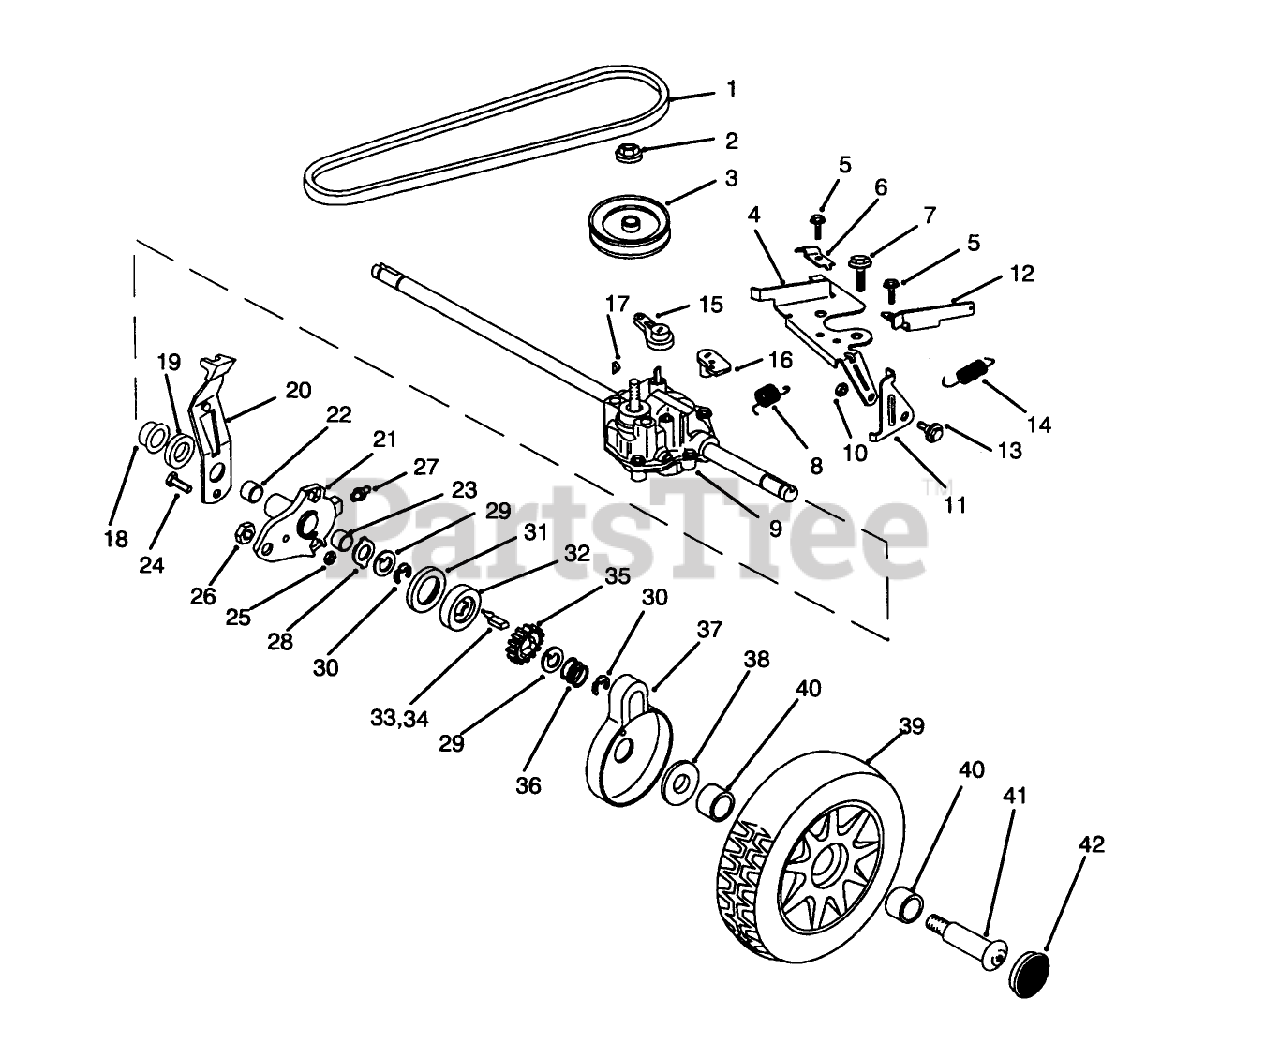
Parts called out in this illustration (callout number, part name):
1	V BELT SM
3	PULLEY TRANS ADAMS
6	CLAMP-CABLE
10	NUT-LOCK, NI
16	ARM - CLUTCH
17	KEY GALGER
18	RING ISO
19	SPACER-SHAFT, AXLE
20	KNOB&SPRING AY.
24	SCREW-HWH
25	NUT-LOCK, NI
26	NUT-JAM, LOCKING
28	WASHER-ARM, PIVOT
29	WASHER-THRUST, KEYED
30	RING-RETAINING,CLIP
31	RING-FRICTION
32	WASHER-CLUTCH
33	KEY-ROCKING, RH
34	KEY-ROCKING, LH
35	GEAR-PINION
36	SPRING-COMPRESSION
38	WASHER-STEPPED
39	WHEEL AND TIRE ASM
41	BOLT-SHOULDER
